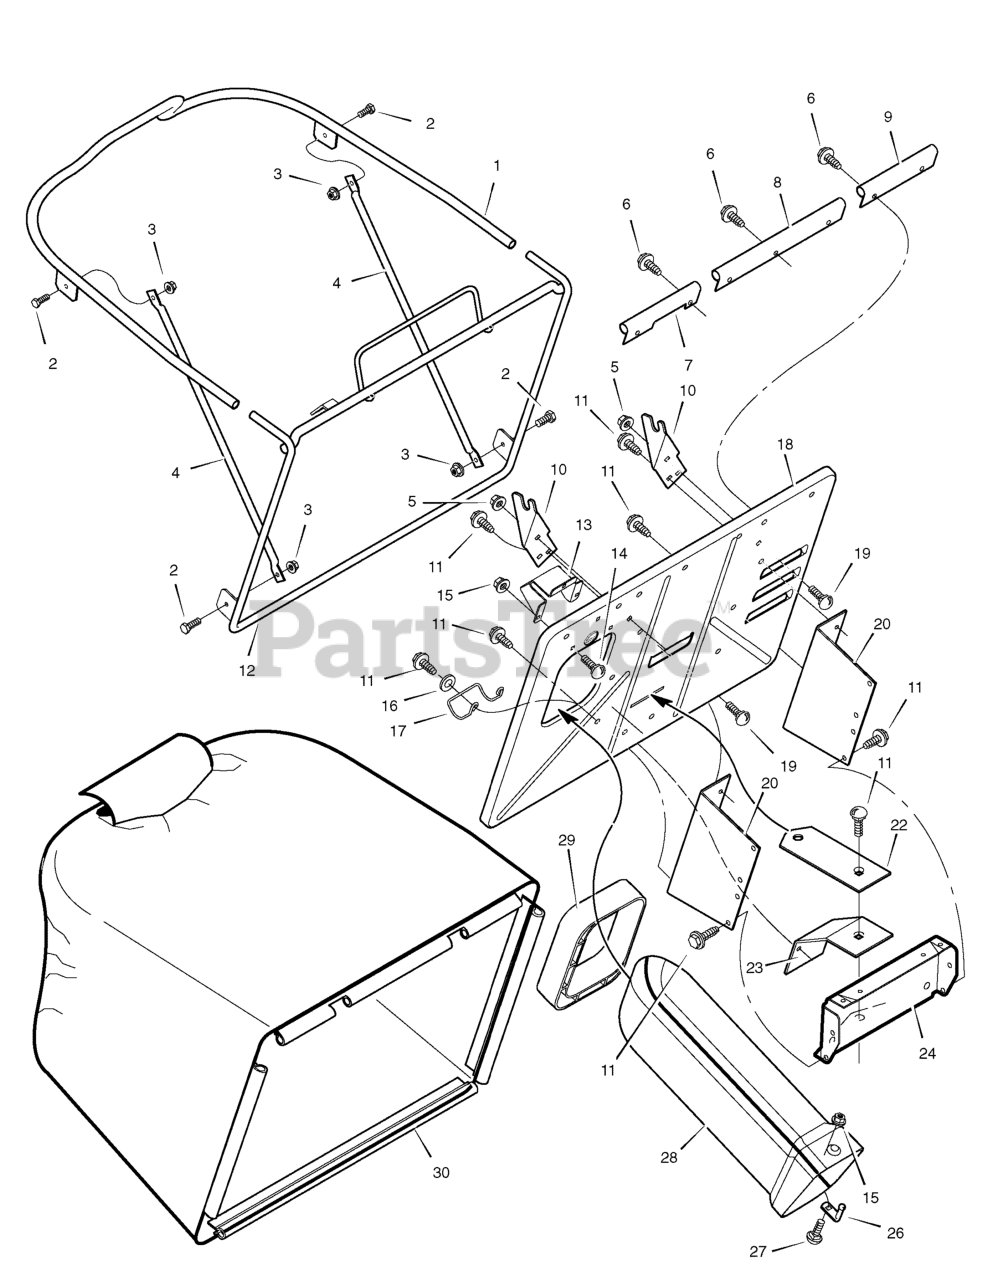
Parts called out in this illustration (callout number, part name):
1	Tube, Top
2	Bolt
3	Nut
4	Strut, Bag
5	Nut, Flange
6	Fastener, Panel
7	Seal, Bag (Right End)
8	Seal, Bag (Center)
9	Seal, Bag (Left End)
12	Assembly, Bag Frame
13	Bracket, Switch
14	Bolt, Carriage
15	Nut, Flange
16	Washer
17	Latch, Spring
19	Bolt, Carriage
20	Bracket, Bagger Mounting
22	Plate, Hitch
23	Bracket, Lower Mounting
24	Plate, Hitch
26	Pin, Latch
27	Bolt, Carriage
28	Tube, Connecting
29	Grommet, Extension Tube
30	Bag, Grass
31	Assembly, Grass Bag
